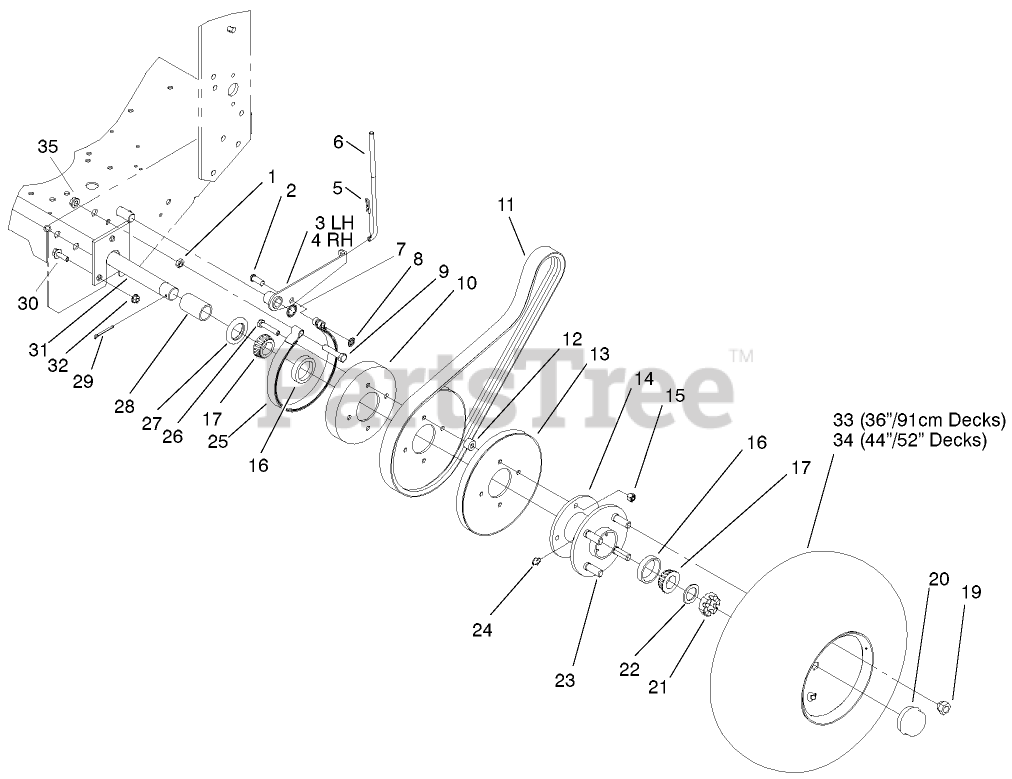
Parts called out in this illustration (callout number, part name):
1	NUT-JAM
2	PIN-CLEVIS
3	ARM-BRAKE, LH
4	ARM-BRAKE, RH
5	PIN-COTTER
6	ROD-BRAKE
7	RING-RETAINING
8	RING-RETAINING, EXTERNAL
9	SCREW-HH
10	DRUM-BRAKE
11	BELT-DRIVE, TRACTION
12	SPACER-PULLEY
13	PULLEY-WHEEL
14	HUB/WHEEL ASM
15	NUT-LOCK, NI
16	BEARING-CUP, TAPERED
17	BEARING-CONE, TAPERED
19	NUT-LUG
20	CAP-DUST
21	NUT-SHH
22	WASHER-SPACER
23	STUD-WHEEL
24	FITTING-GREASE
25	BAND-BRAKE
26	SCREW-HH
27	SEAL-GREASE
28	SPACER-WHEEL
29	PIN-COTTER
30	SCREW-HHF
31	AXLE ASM
32	NUT-HF
34	WHEEL AND TIRE ASM
35	NUT-HHF, WHIZ
